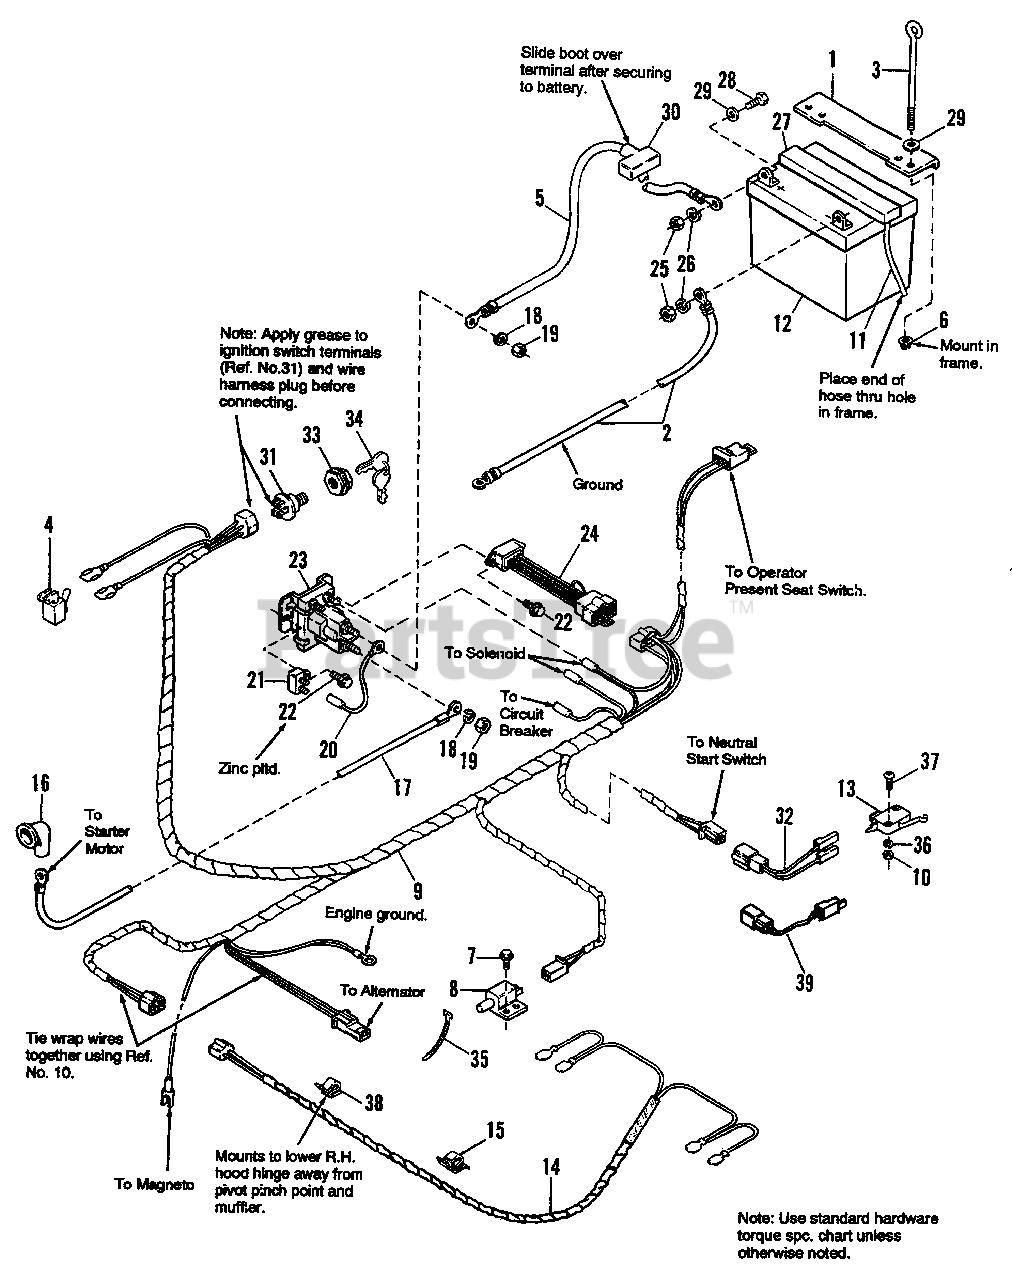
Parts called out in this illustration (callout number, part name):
1	HOLD DOWN, Battery
2	CABLE, Ground (Negative)
3	ROD, Battery Hold Down
4	SWITCH, Headlight
5	CABLE (Positive)
6	NUT, Retainer, 1/4-20
7	SCREW, Taptite #10-24 x 1/2 (Mfg. Nos. 1692156, 1692164)
8	SWITCH, PTO
9	HARNESS, Wiring
10	NUT, Hex, #5-40 (Mfg. Nos. 1682156, 1692164)
11	HOSE, Battery Drain
13	SWITCH, Transmission Interlock (Mfg. Nos. 1692156, 1692164)
13	SWITCH, Transmission Interlock (Mfg. Nos. 1692259, 1692263)
14	WORE ASSY., Headlights
16	COVER, Terminal
18	LOCKWASHER, 5/16
19	NUT, Hex, 5/16-24
21	CIRCUIT BREAKER
22	SCREW, Taptite, 1/4-20 x 5/8, Zinc Pltd.
23	SOLENOID
24	MODULE, Interlock, Seat Switch
25	NUT, Hex, 1/4-20
26	LOCKWASHER, 1/4
27	VENT CAP, Battery
28	CAPSCREW, Hex Hd., 1/4-20 x 3/4
29	WASHER, 1/4
30	BOOT, Insulator
31	SWITCH, Ignition
32	ADAPTOR, Wire (Mfg. Nos.1692156, 1692164)
33	ADAPTOR NUT
35	TIE, Cable (Qty. 3 used on Mfg. Nos. 1692259, 1692283)
36	LOCKWASHER, #5 (Mfg. Nos. 1692156, 1692164)
37	SCREW, Phillips #5-40 x 3/4 (Mfg. Nos. 1692156, 1692164)
38	CUP, Wire
39	ADAPTOR, Wire (Mfg. Nos. 1692259, 1692263)
